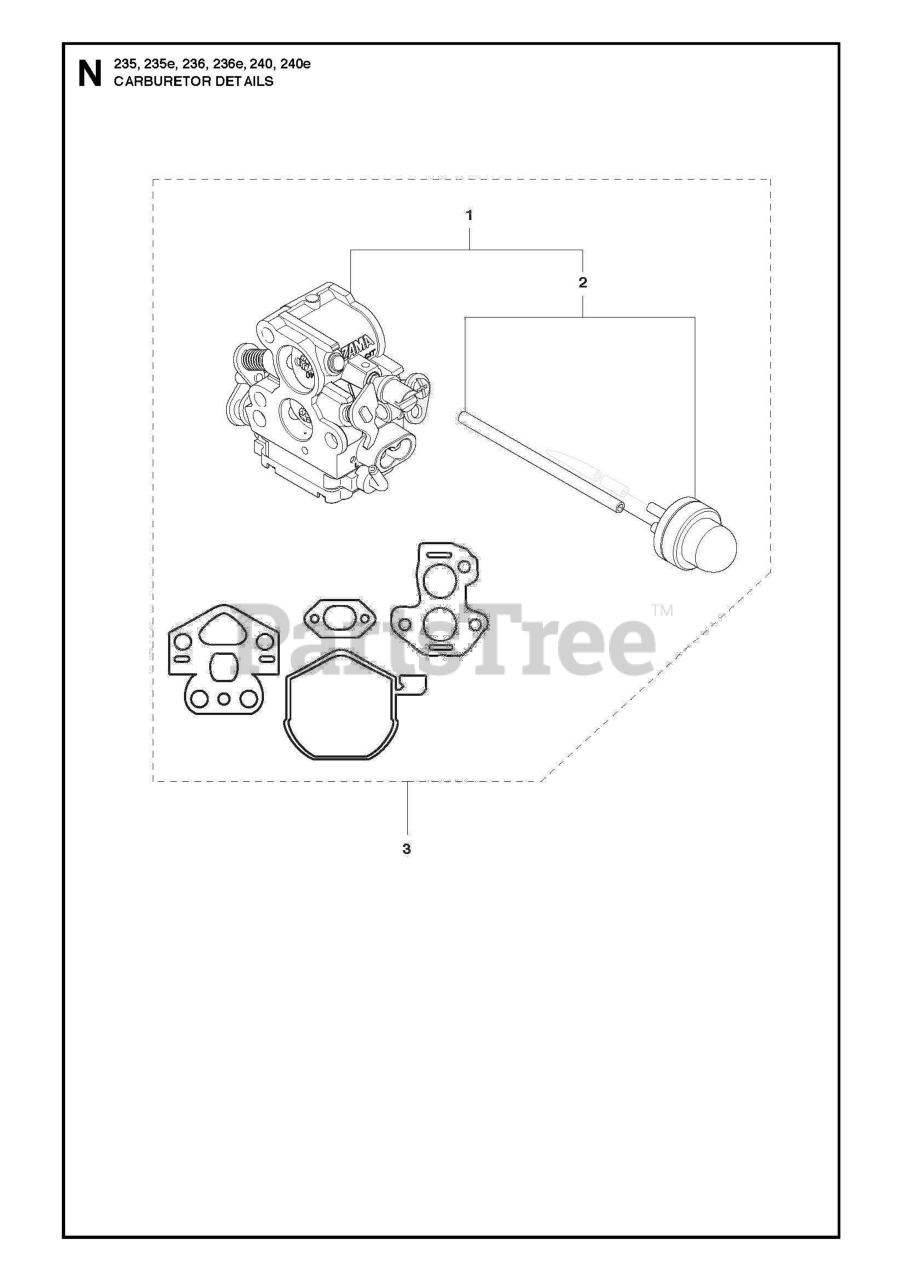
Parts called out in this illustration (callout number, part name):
1	CARBURETTOR 14MM AIR BORE, ANG
2	PURGE & LINE ASSY
3	KIT CARB REPAIR
